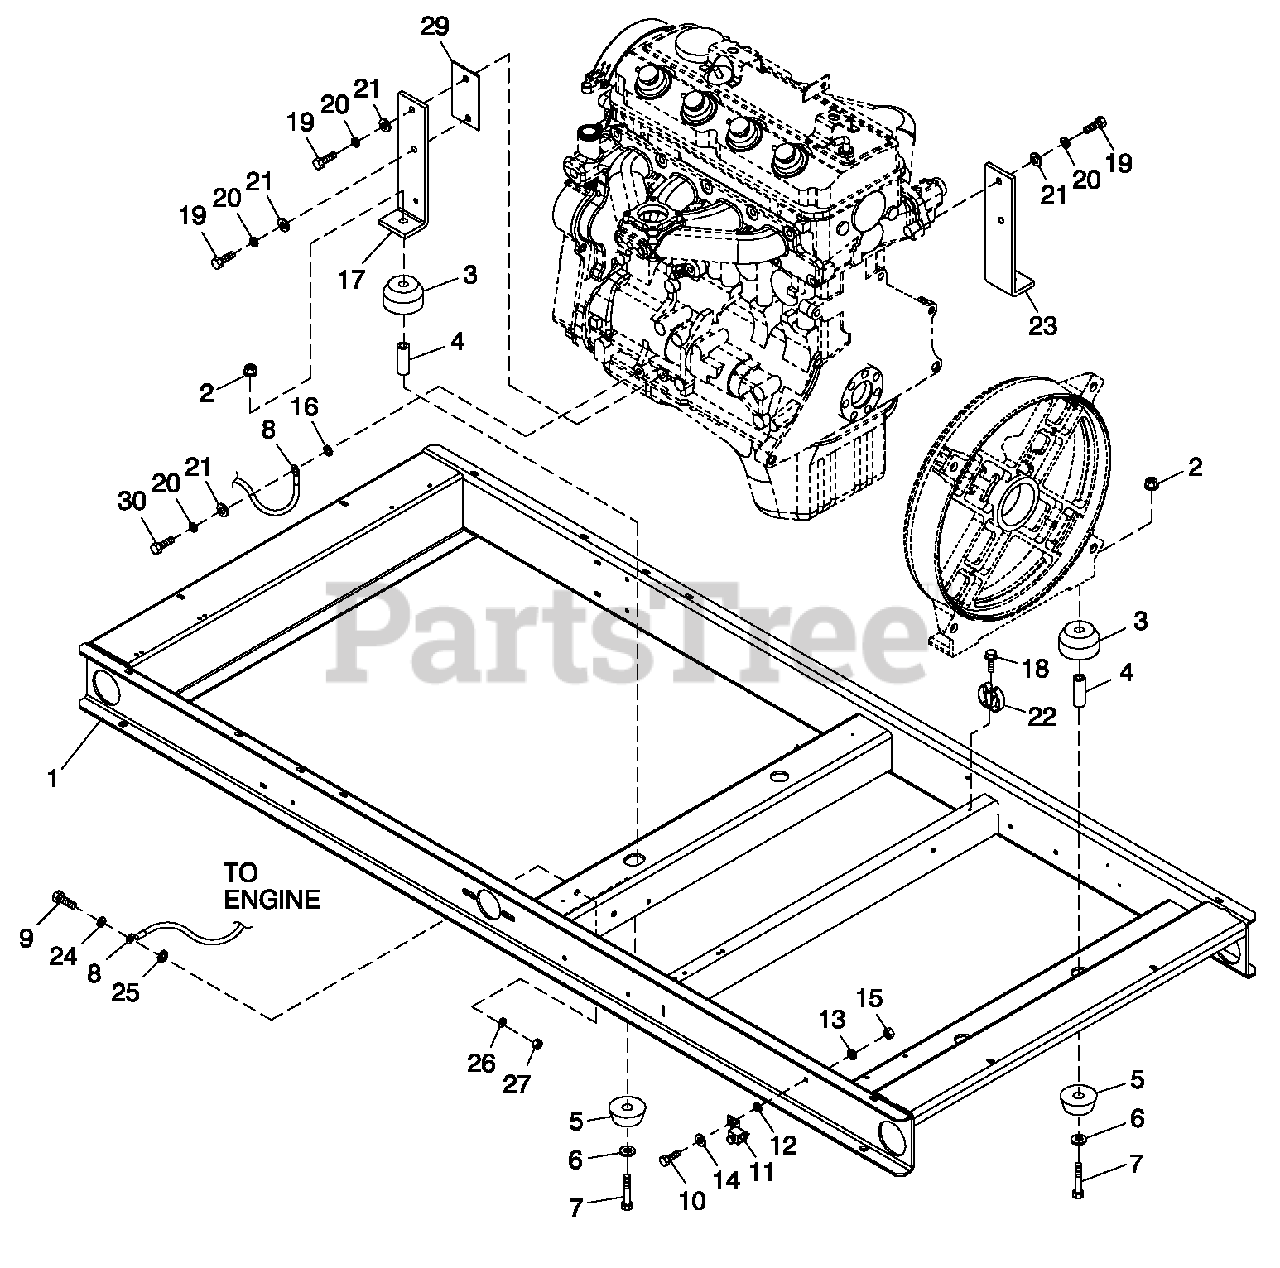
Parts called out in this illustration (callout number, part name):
1	WELDMENT FRAME 2.4L C2 60KW
2	NUT FLANGED HEX M12-1.75
3	DAMPENERVI B RATION 40 BLUE
4	SPACER .49 X .62 X 1.87 PWDR/ZNC
5	DAMPENERVI B RATION
6	WASHER FLAT M12
7	SCREW HHC M12-1.75 X 80 G8.8
8	ASSY W IRE 14.00"
9	SCREW HHC M8-1.25X 30 G8.8
10	SCREW HHC M6-1.0X 16 G8.8
11	LUG SLDLSS #2-#8X 17/64 CU
12	WASHER SHAKEPROOFI NT 1/4
13	WASHER LOCK M6-1/4
14	WASHER FLAT M6-1/4ZINC
15	NUT HEX M6 -1.0 G8YEL CHR
16	WASHER SHAKEPROOF I NT 3/8
17	SUPPORT LH ENGINE 2.4L
18	SCREW HHTT M4-0.7X8BP
19	SCREW HHC M10-1.25 X 30 G8.8
20	WASHER LOCK 7/16
21	WASHER FLAT 3/8-M10ZI NC
22	SPRING CL IP HOLDER .37-.62
23	SUPPORT RH ENG INE 2.4L
24	WASHER LOCK M8-5/16
25	WASHER SHAKEPROOF I NT 5/16
26	WASHER FLAT 5/16-M8ZINC
27	NUT HEX M8-1.25 G8 CLEAR Z I NC
29	SPACER LH ENGINE MOUNT
30	SCREW HHC M10-1.25 X 25 C8.8
